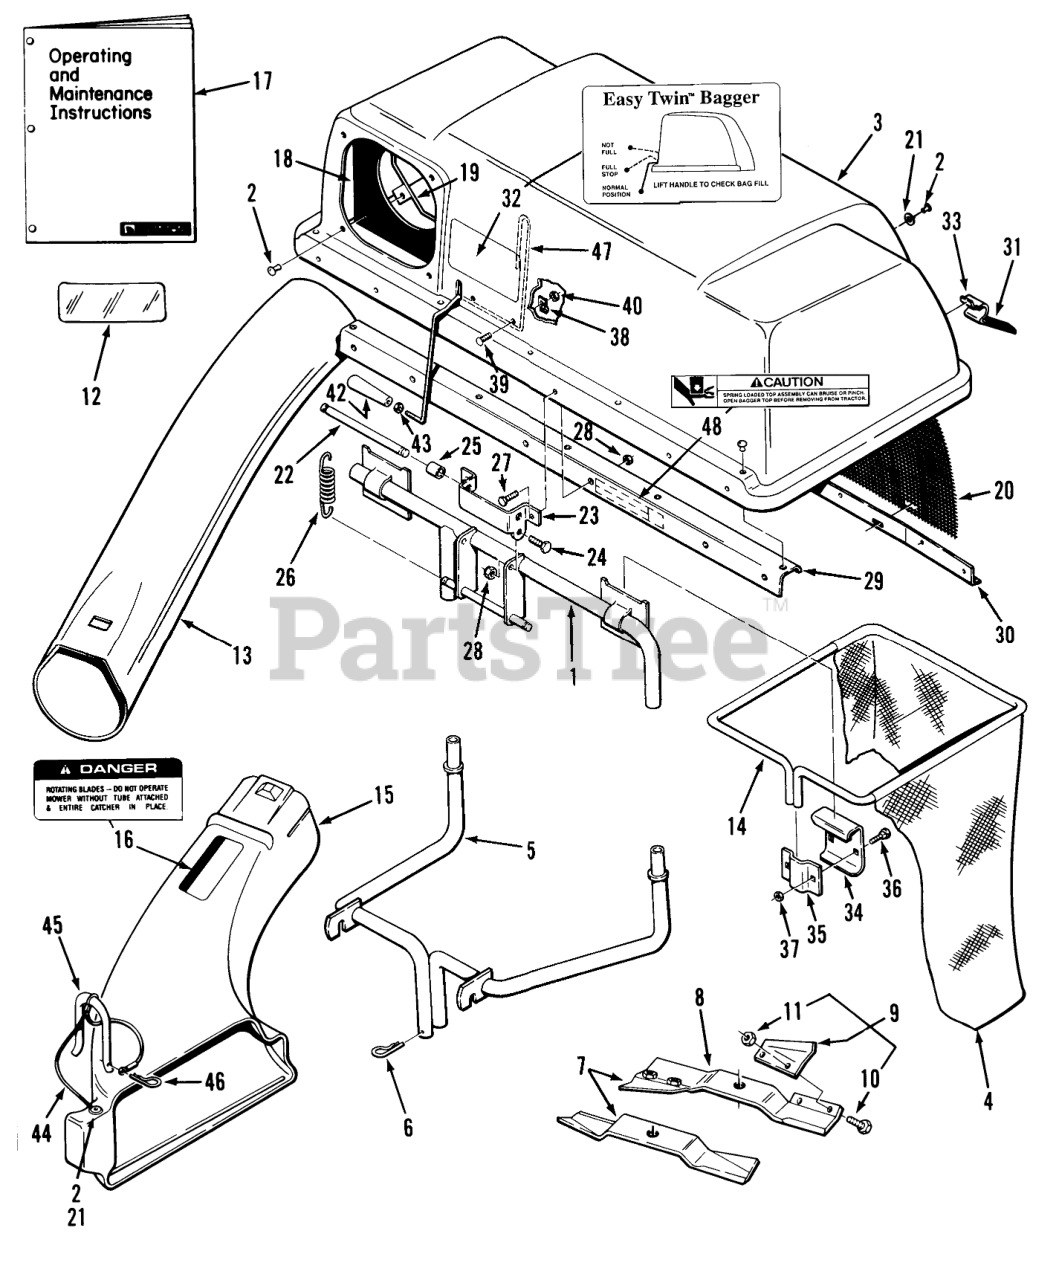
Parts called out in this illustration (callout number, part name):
2	RIVET-BLIND
5	ASM-QUICK ATTACH *B
6	Hairpin
7	KIT-BLADE (SERVICE)
8	ASS'Y-HI LIFT BLADE
9	S/A 37 LIFT TAB KIT
10	BOLT 5/16-18X5/8
11	NUT-HEX
12	DECAL-OVERLAY
13	CHUTE-BAGGER (L)
16	DECAL-DANGER
17	Operating and Maintenance Instructions
19	CLAMP-SEAL
20	SCREEN-BAGGER
22	PIN-SPRING
26	SPRING-EXTENSION
42	HANDLE-TAPERED
44	LANYARD-ELBOW LATCH
45	LATCH-ELBOW
46	Hairpin Cotter
47	FEELER-FILL, BAG
